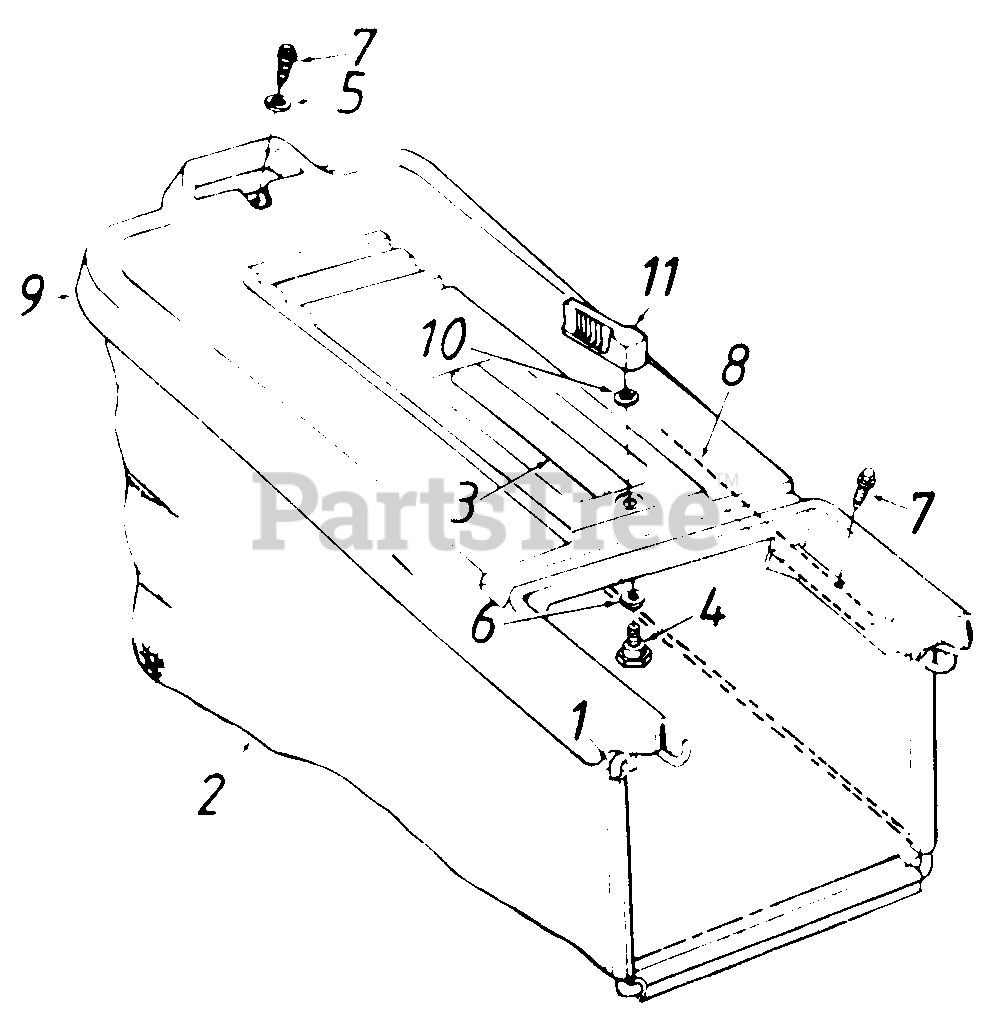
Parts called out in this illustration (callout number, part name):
2	Grass Bag
3	Hardtop Handle
4	Shoulder Bolt
5	Fl-Wash ..281" I D.
6	Bowed Washer
7	Hex L-Wash. AB-Tap Scr. 1/4 x .62"
10	Internal L-Wash. 1/4" I.D.
11	Locking Knob
